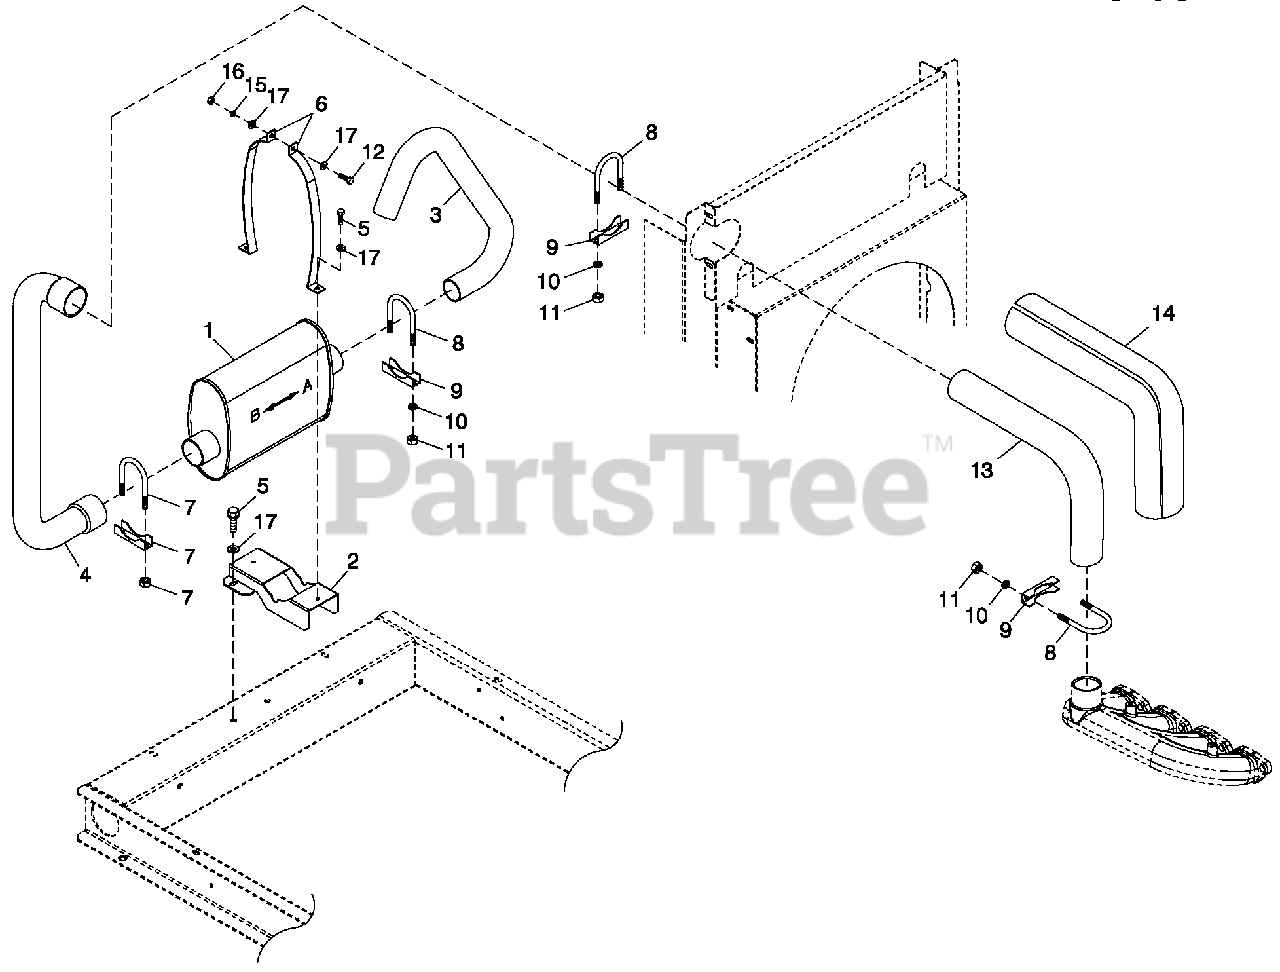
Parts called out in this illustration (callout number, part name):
1	MUFFLER C1
2	MUFFLER SADDLE
3	PIPE EXHAUST OUTLET
4	EXHAUST PIPE LOWER 1.6L
5	SCREW HWHTF M6-1.0 X 16
6	MUFFLER STRAP
7	BOLT U 5/16-18 X 2-1/4
8	BOLT U 5/16-18 X 2.09
9	SADDLE 2 INCH
10	WASHER LOCK M8-5/16
11	NUT HEX 5/16-18 STEEL
12	SCREW HHC M6-1.0 X 30 G8.8
13	EXHAUST PIPE UPPER 1.6L SS
14	EXHAUST BLANKET 500MM LONG
15	WASHER LOCK M6-1/4
16	NUT HEX M6 X 1.0 G8 YEL CHR
17	WASHER FLAT 1/4-M6 ZINC
